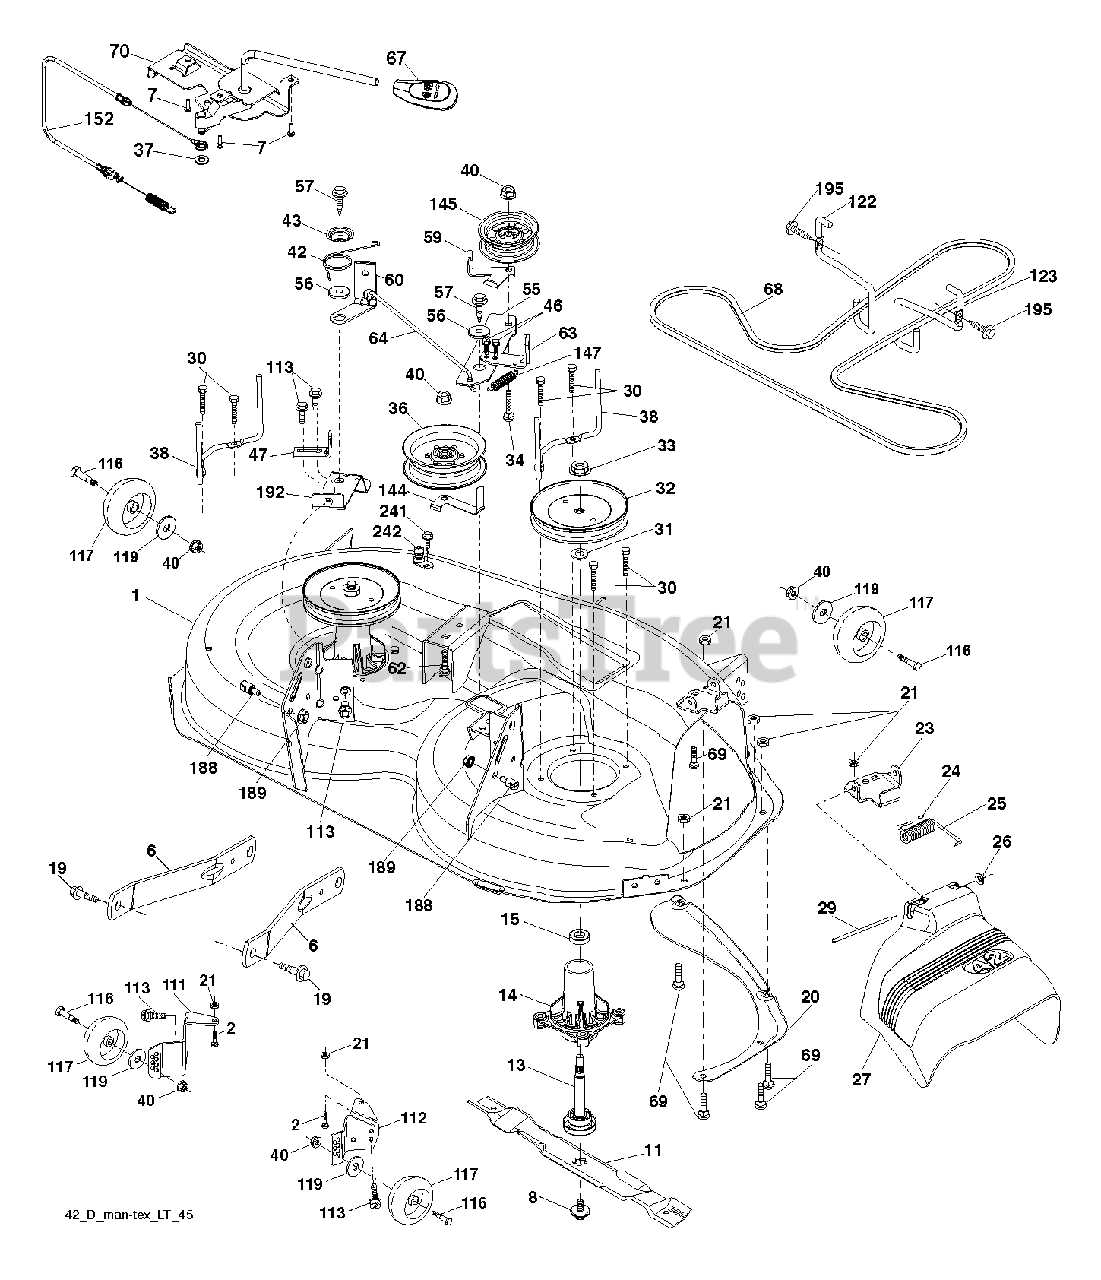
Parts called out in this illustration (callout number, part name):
2	BOLT
6	ARM.SUSPENSION.MOWER.R
7	SCREW.#10 X 0.750.BOS (2 2)
8	BOLT.WASHER.ASM.7/16-2
11	42" HI-LIFT BLADE
13	SHAFT.ASM.MDRL.N/GREASE.38
14	HOUSING.MANDREL.4PT.
19	BOLT.SHOULDER
20	BAFFLE.VORTEX
21	LOCKNUT
23	BRKT.DEFLECTOR.38"2005+
24	CAP-SLEEVE LT
25	SPRING.TORSION.DEFLECT
26	NUT PUSH M
27	SHIELD.DEFLECTOR.MOWER.42"BLAC
29	ROD.HINGE
30	SCREW, WASHER HEAD
31	WASHER.SPACER.MANDREL
32	PULLEY.MANDREL.5.438.PD
33	NUT.FLANGE.LOCK.TOP
34	BOLT.3/8-16X1.50
36	PULLEY.IDLER.2006
38	KEEPER.BELT.MANDREL.PULLEY
40	NUT LOCK FLG 3/8-16 UNC
42	SPRING.TORSION.BRAKE
43	SRPING.TORSION.RETAINE
46	SCREW.1/4-20X5/8
47	BRKT.CLUTCH.CABLE
55	IDLER.ARM.42"
56	SPACER.RETAINER
57	SCREW 3/8-16X1
59	GUARD, BELT
60	ARM BRAKE MOWER
62	BOLT
64	LINK BRAKE
67	HANDLE.CLUTCH.CABLE.LT
68	BELT.DECK.DRIVE.42"
69	BOLT
70	CLUTCH.ASM.MANUAL
111	BRKT.WHEEL.GAUGE.LH.42"
112	BRKT.WHEEL.GAUGE.RH.42"
113	BOLT.5/16HEX.WHS.HD
116	BOLT M
117	WHEEL.GAGE.HALF.SPOKED
119	WASHER
122	KEEPER BELT ENGINE LH
123	KEEPER BELT RH
144	KEEPER.BELT.MOWER
145	PULLEY.IDLER.48"PRIMARY
147	RETURN SPRING
152	CABLE.CLUTCH.MANUAL.
188	STUD.FASTNER.W/ANTI-ROTATE
189	NUT LOCK HEX FLANGE 5/16-18
192	BRKT.BRAKE.STAND.LH.
195	SCREW, 3/8-16X3/4
241	SCREW.TT.#10-32X.5.3/8.FLANGE
242	PORT.WASHOUT
